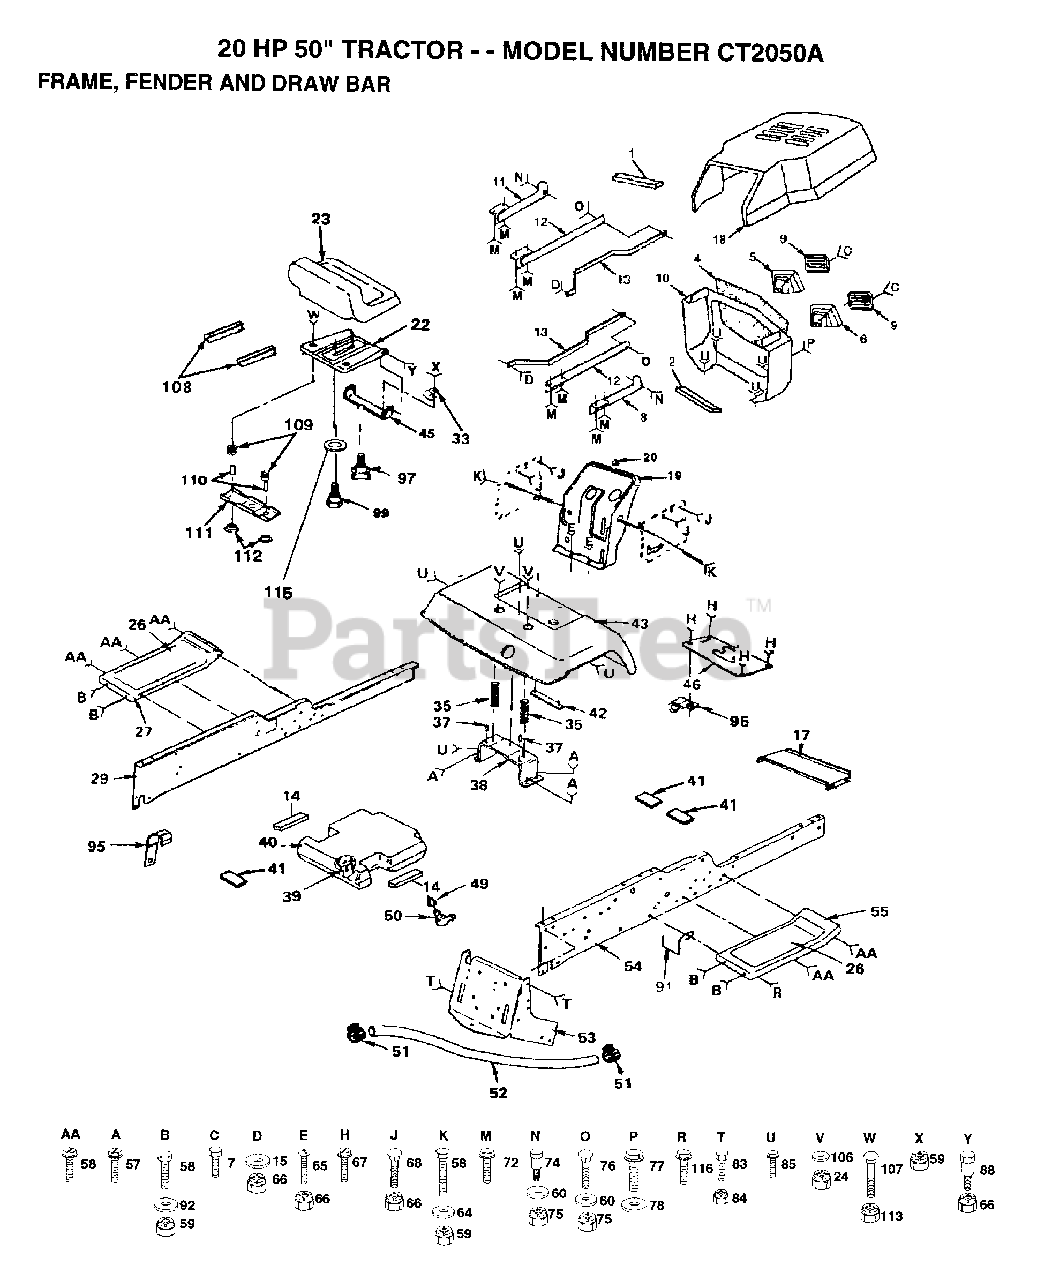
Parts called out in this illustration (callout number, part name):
1	FOAM STRIP T
8	STRAP ASSY T
11	STRAP ASSY T
12	STRAP ASSY-REAR T
14	PAD IDLER TI
15	WASHER M
20	PLUG-DASH T
24	NUT
26	FOOTREST PAD
33	CLIP T
35	SPRING COMPRESSIO
37	NUT-PUSH YT
41	PAD-SPACER LT
46	SADDLE.6SP.GT
49	BUSHING OUTLET T
50	STEM, TANK FUEL
51	HOSE CLAMP
57	SCREW
64	WASHER
65	SCREW
67	SCREW
68	BOLT
74	BOLT T
76	"BOLT,SHOULDER"
77	SCREW HEX SLTP
83	BOLT
84	NUT GTV
85	SCREW LT
91	BELT RETAINER GT
92	WASHER
97	"KNOB 1/2"" YT"
99	"BOLT,SHOULDER"
106	WASHER
107	BOLT, CARRIAGE
108	STRIP FORM
109	SPRING COMPRESSED
110	SPACER SPLIT
111	BRKT SWITCH
112	BUSHING
115	WASHER
116	SCREW GTV
